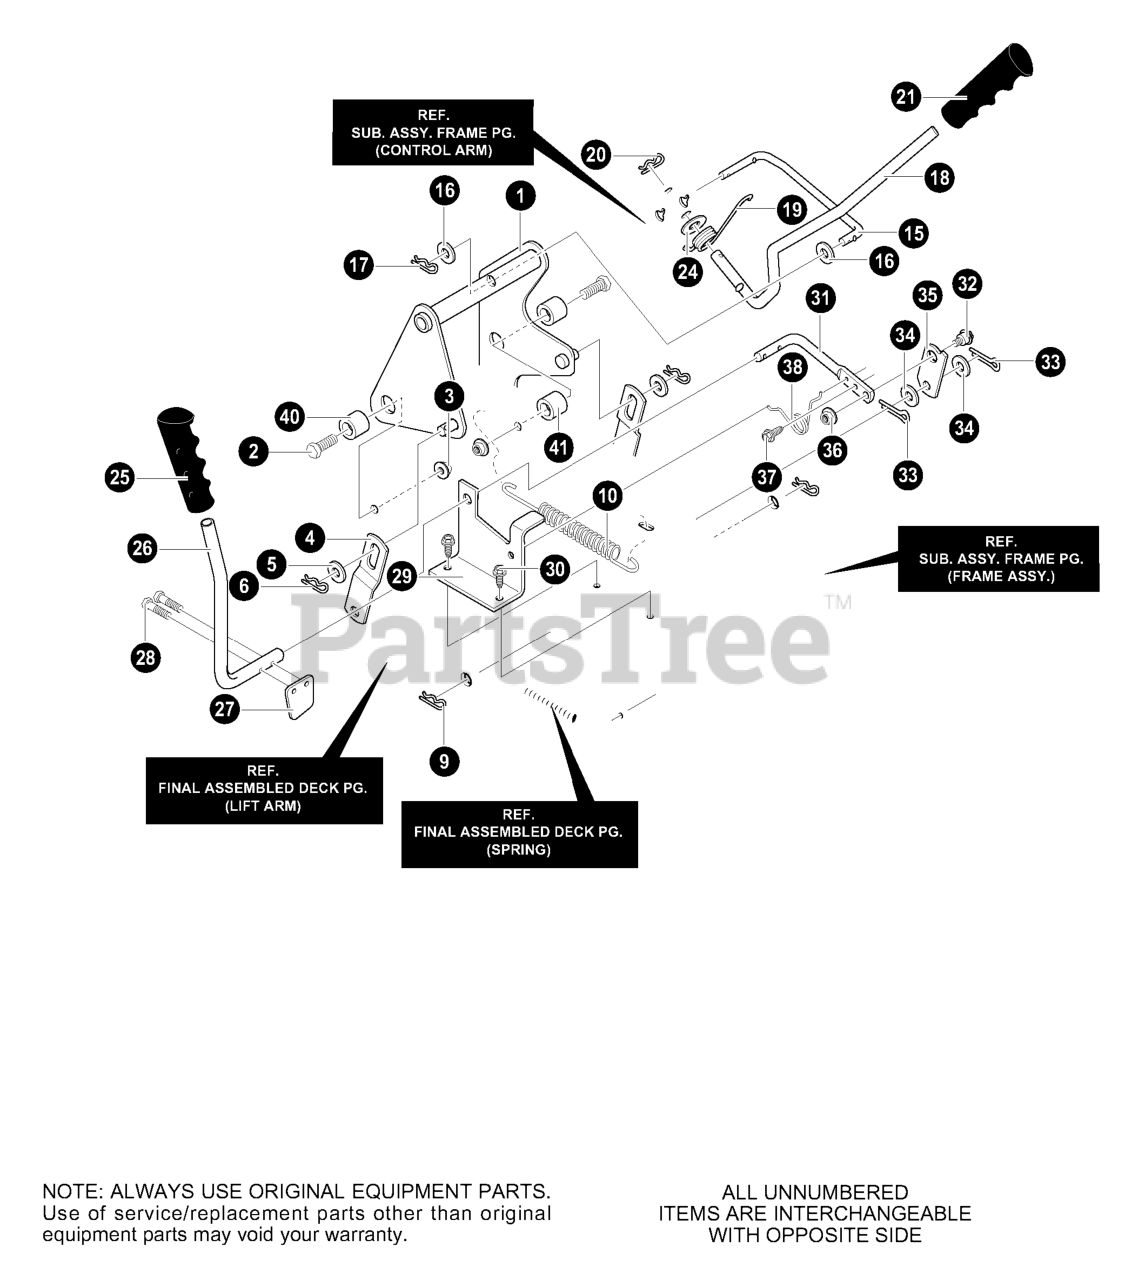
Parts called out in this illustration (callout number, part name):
1	ASSEMBLY, LIFT ARM
2	SCREW,1/2-13X1.50
3	NUT, 1/2-13 LOCK
4	BRACKET, LIFT LINK
5	WASHER,FLAT
6	PIN, HAIR
9	PIN, HAIR
10	SPRING, EXTENSION 9.82X1.01 OD
15	LINK - LIFT HANDLE
16	WASHER, FLAT
17	PIN, HAIR
18	HANDLE, LIFT
19	TORSION SPRING
20	PIN, HAIR
21	GRIP,LIFT
24	WASHER, FLAT .550X1.00X11
25	GRIP
26	PTO HANDLE
27	ZINC PADDLE, SWITCH
28	SCREW, THREAD FORM
29	BRACKET, PTO
30	SCREW, 5/16-18 x 0.50
31	ZINC LEVER, PTO
32	BOLT, .50X.75 HHSH 3/8-16
33	PIN, HAIR
34	WASHER, FLAT .518X.87X16
35	ZINC LINK PTO
36	NUT, 3/8-16 HWDFLLK MACK
37	SCREW, 5/16-18 x 0.75
38	TORSION SPRING
40	SPACER
41	SPACER, SLEEVE
